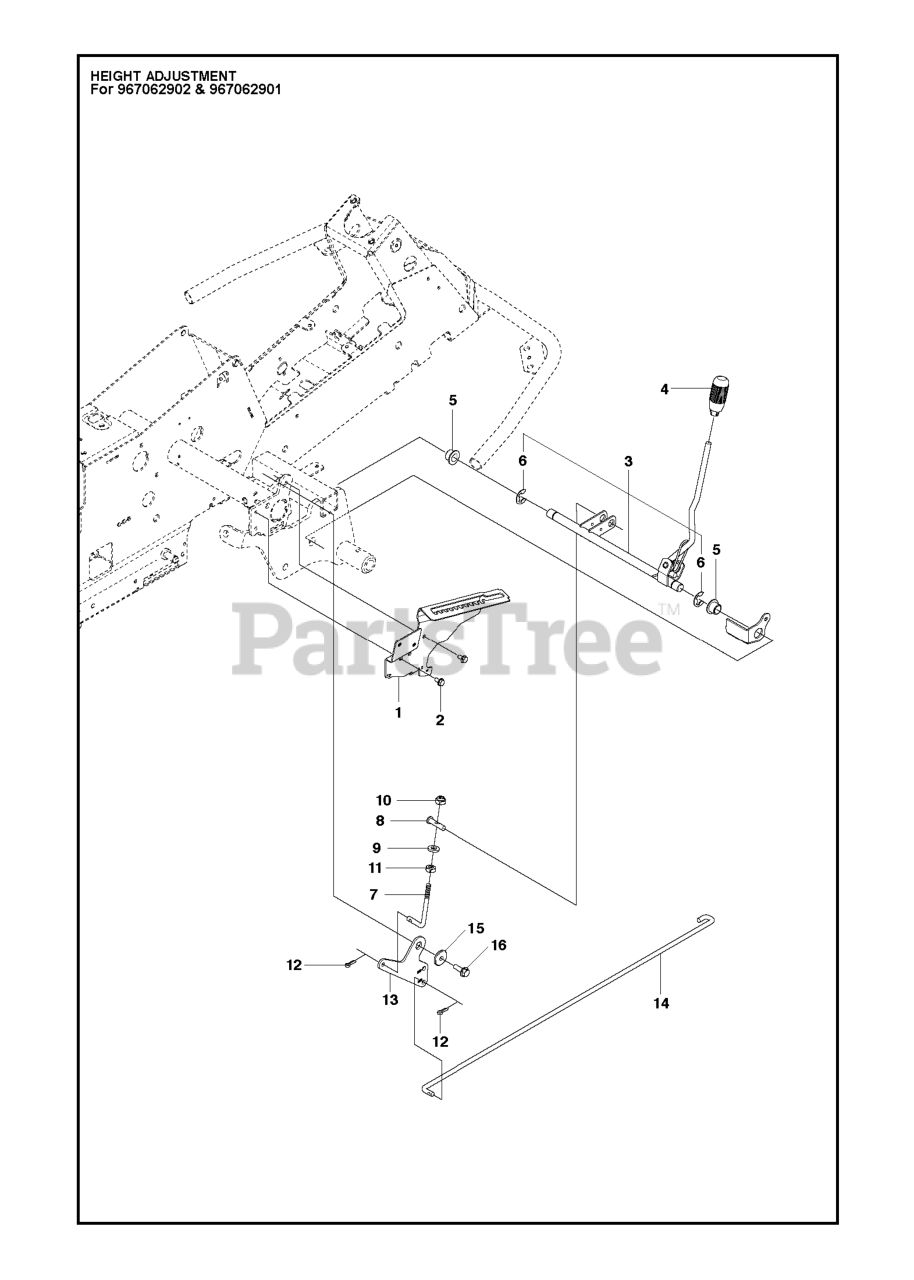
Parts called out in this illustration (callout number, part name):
1	BRACKET ASSY
3	HEIGHT ADJUSTER
4	GEAR STICK KNOB
5	BUSHING
9	WASHER
10	LOCKNUT M8
11	NUT
14	CONNECTION ROD
15	WASHER
16	BOLT
